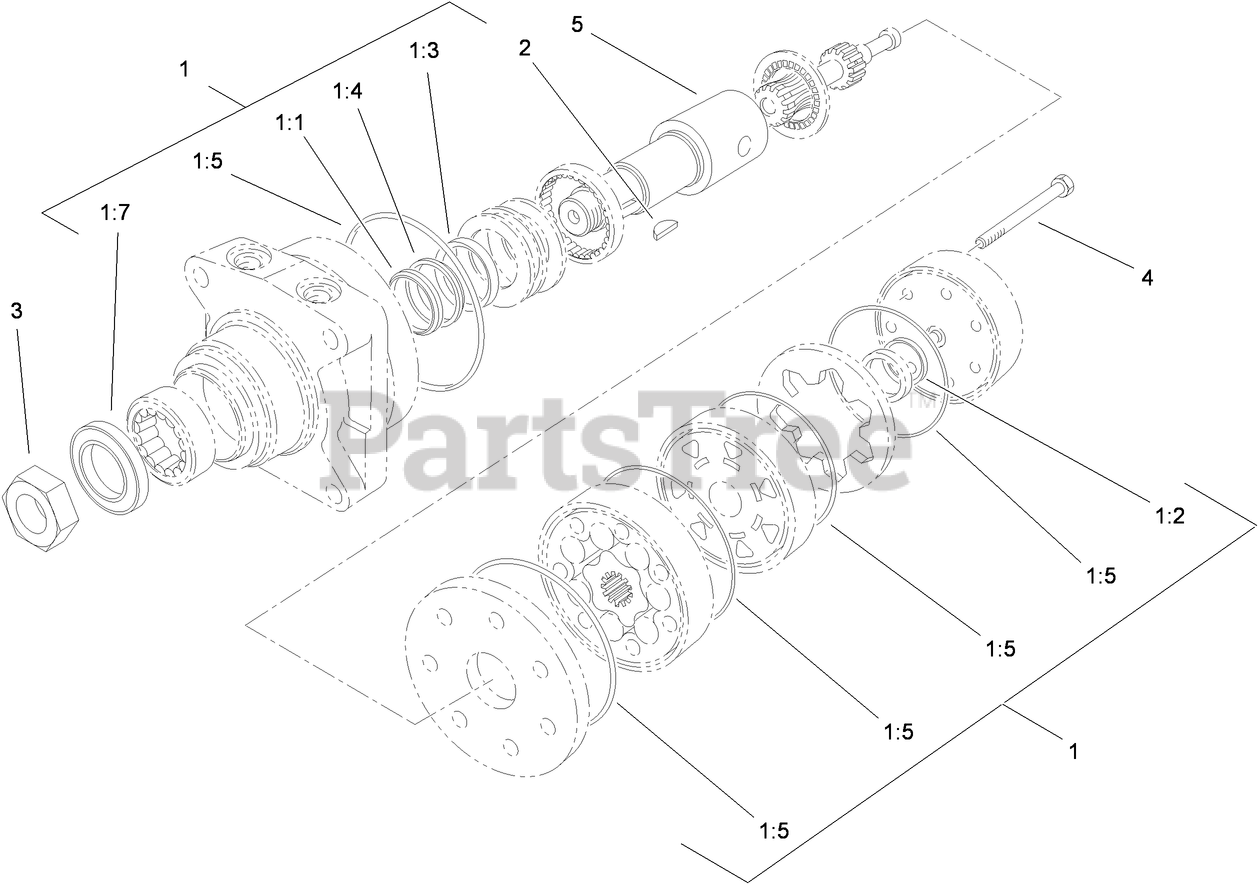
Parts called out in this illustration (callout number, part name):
1	SEAL KIT
1:1	Ring-Back Up
1:2	Seal-Commutator
1:3	SEAL-SHAFT (VITON)
1:4	WASHER-BACK UP, STEEL
1:5	RING-SEAL (VITON)
1:7	Seal-Dirt and Water
2	KEY-WOODRUFF
3	NUT-MOTOR, WHEEL
4	BOLT-SPECIAL
5	SHAFT-COUPLING
